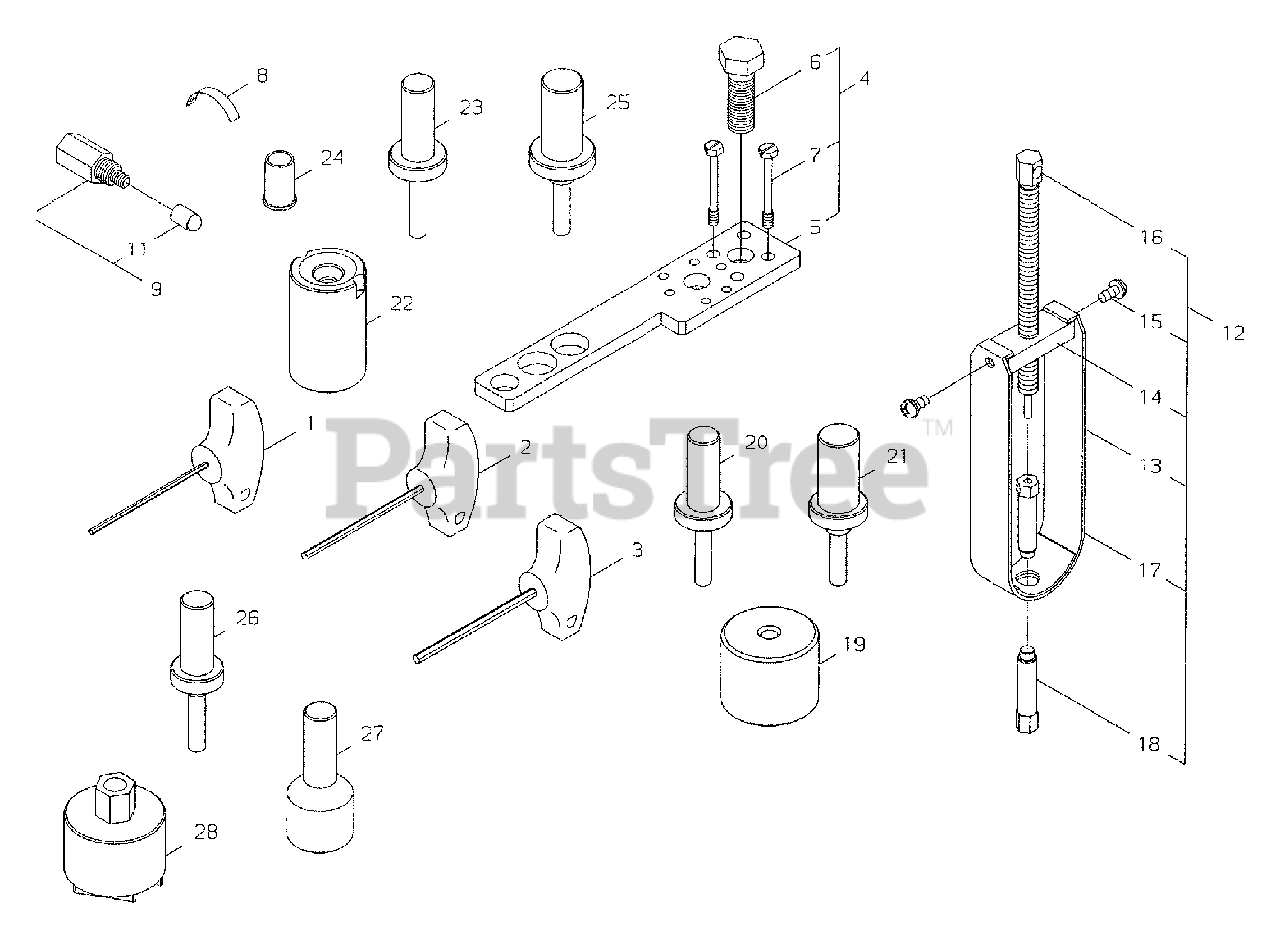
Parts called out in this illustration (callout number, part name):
1	T-WRENCH - 3mm
2	T-WRENCH - 4mm
3	T-WRENCH - 5mm
4	PULLER ASSY
5	LEVER
6	BOLT, CENTER
8	AIR GAP GAUGE
9	STOPPER ASSY
11	CAP
12	PULLER TOOL KIT
13	PULLER
14	BOSS
15	SCREW - 6X12
16	BOLT
17	PIN - ADAPTOR
18	GUIDE PIN
19	HOLDER M
20	SEAL, OIL
21	ROD - 6202
23	SEAL, OIL
24	SEAL, OIL
25	ROD - 6203
